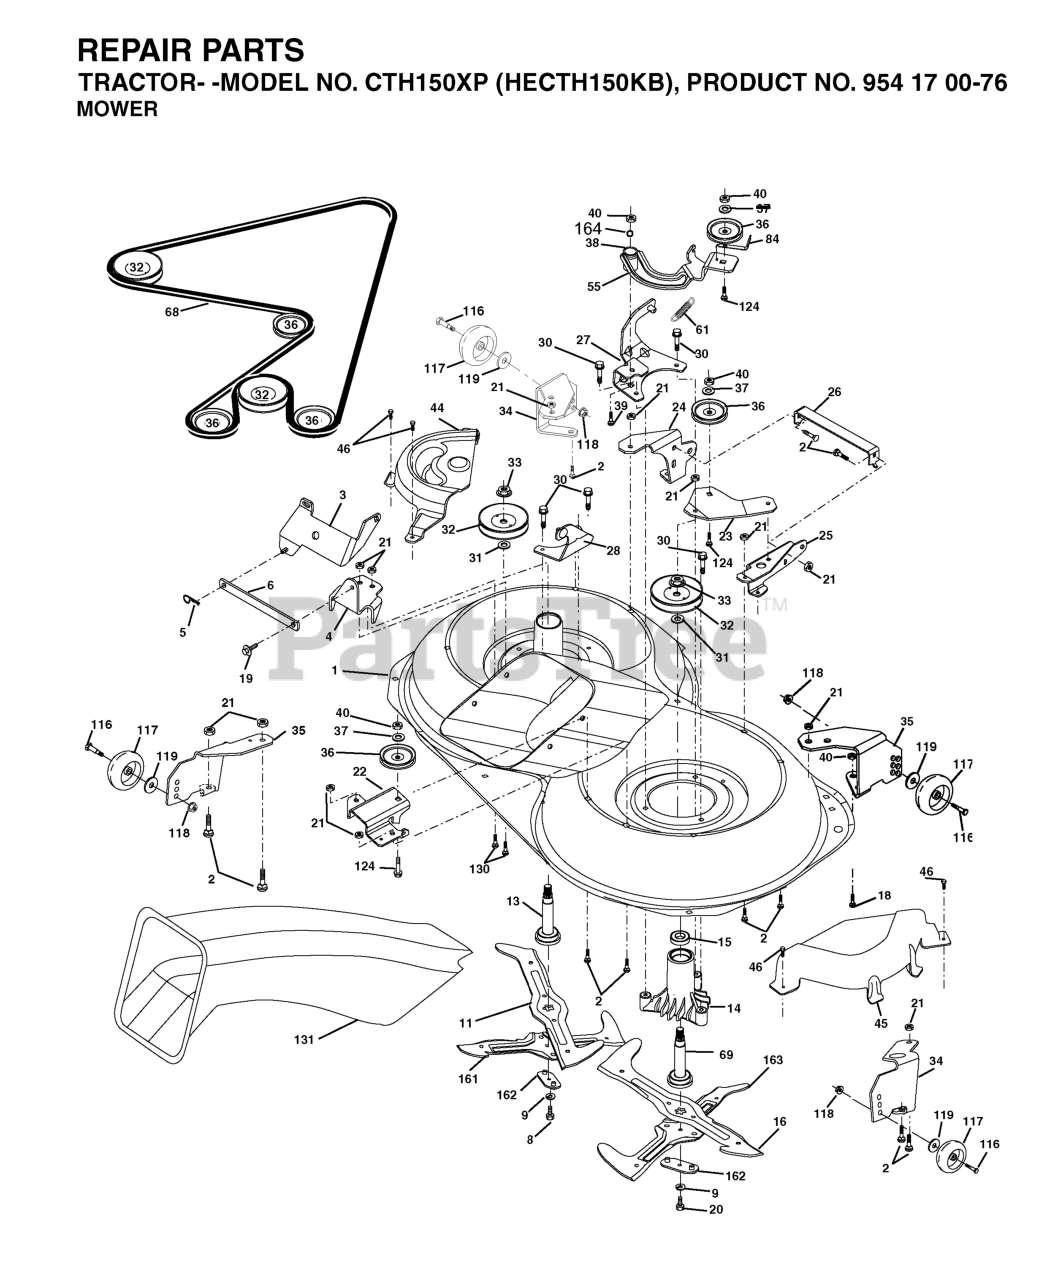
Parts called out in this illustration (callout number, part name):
1	Housing Asm. Mower 107 CRD
2	RP BOLT 5/16-18 X3/4 ZN/YEL GR
5	RETAINER-SPRNG RB
5	RETAINER SPRING
6	BAR.SWAY.92.CRD
8	BOLT.3/8-24X1.25 GR8
9	LOCKWASHER
11	BLADE.3N1.LH.CRD
13	SHAFT ASM VENT
14	HOUSING.MANDREL.VENTED (MACHD)
16	BLADE.3N1.RH.CRD
19	BOLT SHD 5/16-18
20	BOLT.3/8-24X1.25GR8. LHTHRD
21	LOCKNUT
22	BRACKET.IDLER.RR.107.CRD
25	BRACKET.SUSPENSION.RF.107.CRD
26	BRACE.SUPT.SUSP.FRT.CRD
28	BRACKET
30	SCREW, WASHER HEAD
31	WASHER.SPACER.MANDREL
33	NUT, FLG TOPLOCK 9/16"
36	PULLEY.IDLER.4.25
37	WASHER
40	NUT LOCK FLG 3/8-16 UNC
45	COVER.MANDREL.RH.CRD
46	SCREW.1/4-20X5/8
55	ARM.IDLER.107.CRD
68	HEX-BELT 107 MOWER
69	SHAFT.ASM.W/LWR.BRG.RH.THREAD
84	KEEPER, BELT IDLER
116	SHOULDER BOLT
117	WHEEL GAGE DONUT
118	LOCKNUT
119	WASHER.5/16.FLAT.STE.STD.
124	BOLT.3/8-16X1.50
130	BOLT.CARR.SQNK.5/16-18UNC.X3/4
131	CHUTE BAGGER
163	BLADE.CROSS.RH.CRD.107
164	BRNG T
